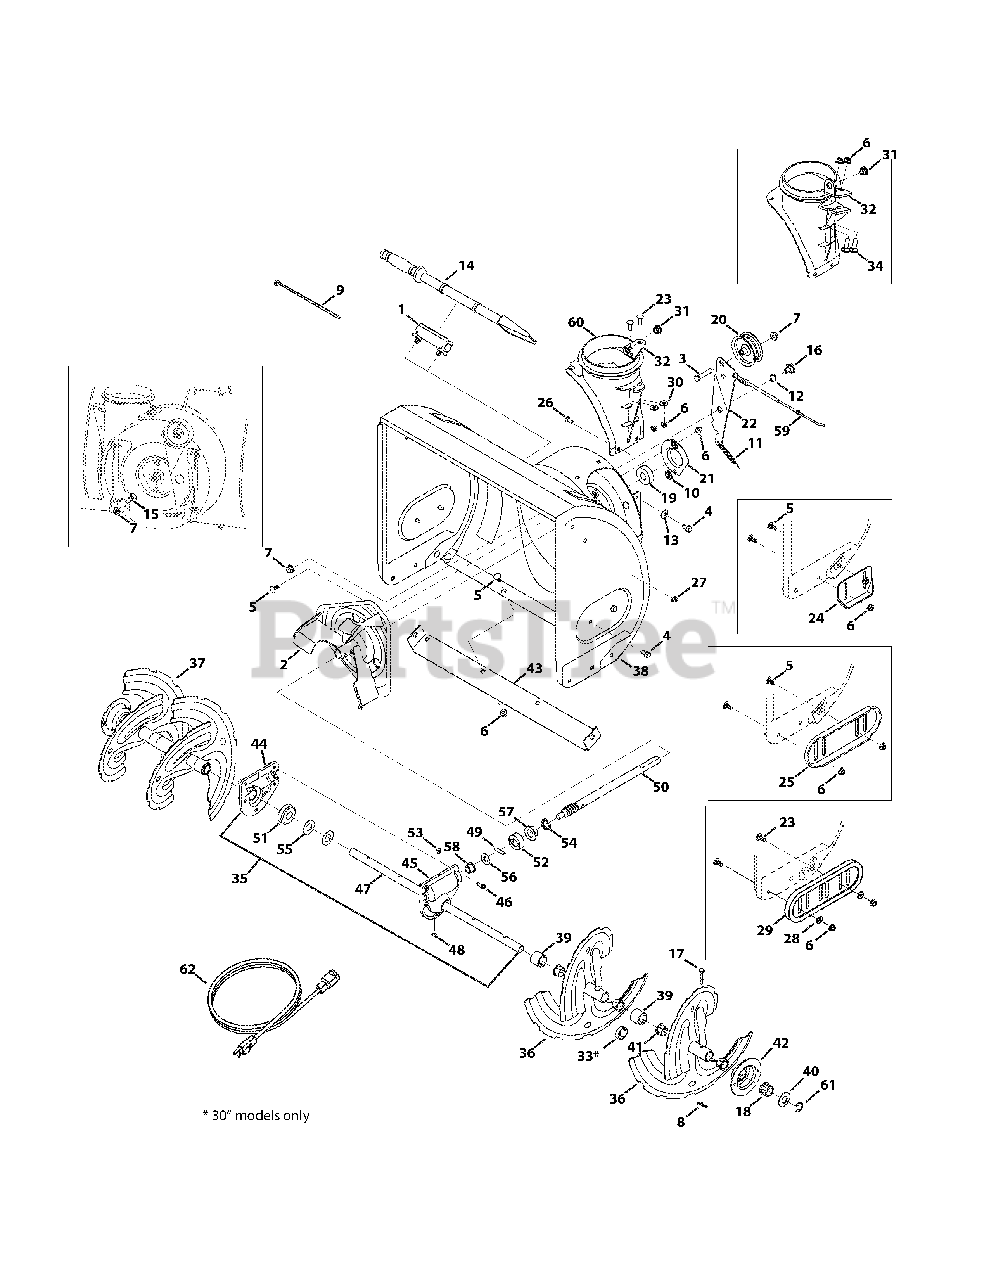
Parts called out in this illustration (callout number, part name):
1	Cleanout Tool Mount
2	Impeller Assembly, 12"
3	Hex Screw, 3/8-16 x 1.75
4	Hex Washer Screw, 5/16-18 x .750
5	Carriage Bolt, 5/16-18 x .750
6	Flange Lock Nut, 5/16-18
7	Flange Lock Nut, 3/8-16
8	Bow-Tie Cotter Pin
9	Cable Tie, 3/16 x .05 x 7.4
10	Push Nut, .25 Dia.
11	Extension Spring
12	Wave Washer, .625 x .885 x .015
13	Bell Washer, .340 x .872 x .060
14	Chute Cleanout Tool
15	Shoulder Bolt, .496 x .336 x 3/8-16
16	Shoulder Screw, .625 x .17 x 3/8-16
17	Shear Pin, .25 x 1.50
18	Hex Flange Bearing
19	Ball Bearing, .75 ID x 1.85 OD
20	Idler Pulley, 2.75 OD
21	Bearing Housing, 1.85 ID
22	Auger Idler Bracket
23	Carriage Screw, 5/16-18 x 1.00
24	Slide Shoe, Standard Steel
24	Skid Shoe Kit, Standard Polymer
25	Deluxe Skid Shoe
26	Carriage Screw, 1/4-20 x .75
27	Flange Lock Nut, 1/4-20
28	Washer, Flat, .349 x .879
29	Slide Shoe, Poly
30	Flat Washer, .349 x .879 x .063
31	Plastic Bushing, .380 ID
32	Chute Crank Bracket
33	Spacer, 1.250 x .75 ID x 3/16 LG
34	Carriage Bolt, 5/16-18 x 1.00
35	Gearbox Assembly, 22"
36	Spiral Assembly, LH
37	Spiral Assembly, RH
38	Auger Housing Assembly, 22"
39	Spacer, 1.2500 x .75 ID x 1.00
40	Flat Washer, .76 x 1.49 x .06
41	Flange Bushing, .800 ID x .910 OD
42	Hex Bearing Housing
43	Shave Plate, 22"
44	Housing Assembly, RH
45	Housing Assembly, LH
46	Hex Washer Screw, 1/4-20 x .750
47	Auger Axle, 22"
48	Hi-Pro Key
49	Dowel Pin, .25 OD x 1.25 LG
50	Worm Shaft, .75 OD
51	Worm Gear 20 T
52	Thrust Collar, .756 ID x .600
53	Plug, 1/4 x .437
54	Oil Seal, .75 x 1.131 x .188
55	Flat Washer, .760 ID x 1.50 ID
56	Flat Washer, .51 x 1.12 x .06
57	Flange Bearing, .75 ID x 1.0 OD x .59
58	Flange Bearing, .50 ID x .75 OD x .59
59	Auger Drive Cable
60	Chute Adapter, 5"
61	E-Ring, .750
62	3-Prong Extension Cord
